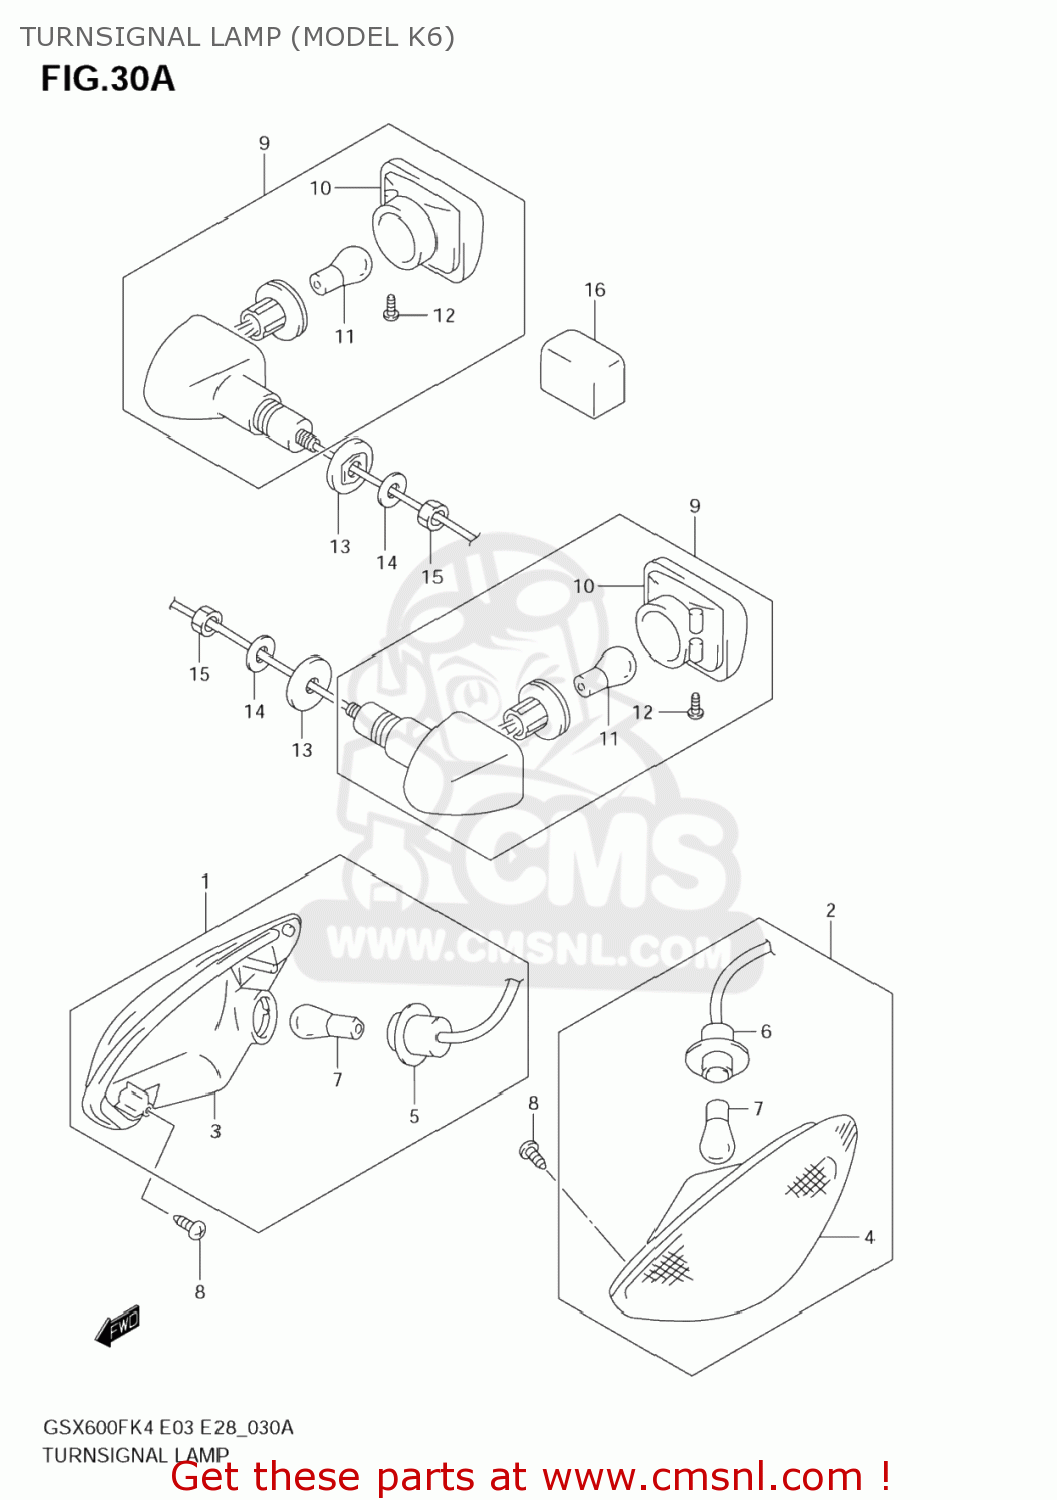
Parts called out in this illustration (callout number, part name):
1	LAMP ASSY,FR TURN SIGNAL,R
2	LAMP ASSY,FR TURN SIGNAL,L
3	LAMP UNIT,R
4	LAMP UNIT,L
5	SOCKET & CORD,R
6	SOCKET & CORD,L
7	BULB(12V21W,AMBER)
8	SCREW
9	LAMP ASSY,RR TURNSIGNAL,R
10	LAMP UNIT
11	BULB(12V21W,AMBER)
12	SCREW
13	SPACER,RR TURNSIGNAL
14	WASHER(10.5X30X2.3)
15	NUT
16	RELAY ASSY,TURNSIGNAL LAMP
